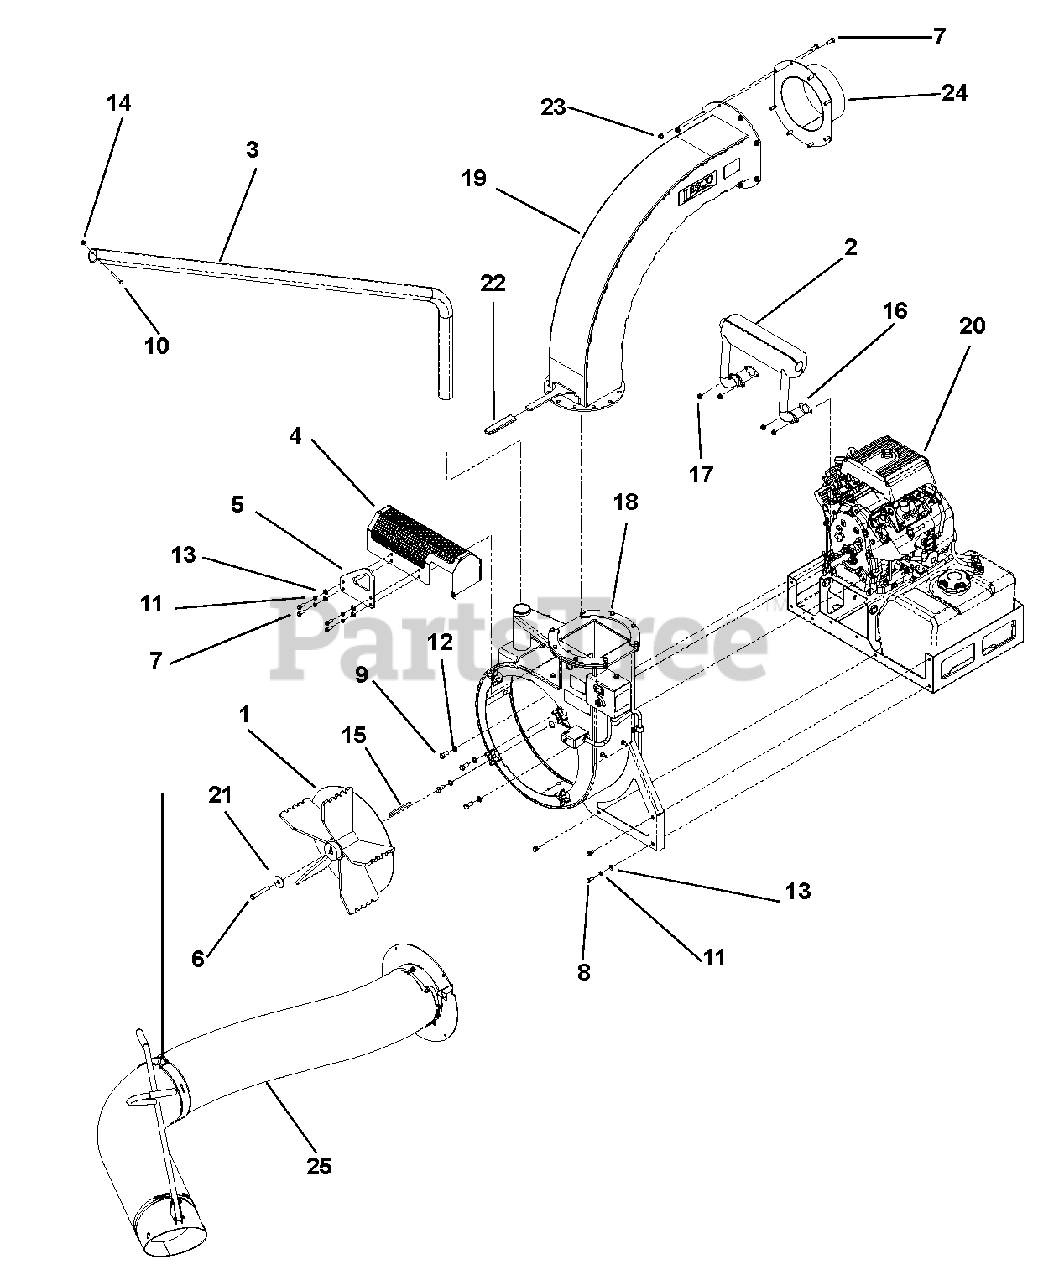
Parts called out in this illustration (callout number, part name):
1	Weldment, Impeller 5 Blade Balanced
1	Weldment, Impeller 4 Blade Balanced
2	Muffler, Subaru 20 HP & 22 HP
2	MUFFLER, SUBARU
3	Support Arm
4	Weldment, Muffler Shield
5	Blower Lift Plate
6	Bolt, Hex .44-20 x 3.00 Grade YZ EP80
6	Bolt, Hex .38-24 x 3.00 Grade YZ EP80
7	Bolt, Hex .31-18 x 1.00 Grade 5 YWZC
8	Bolt, Hex .31-18 x .75 Grade 5 YWZC
9	Bolt, Hex .44-14 x .88 Grade 5 EP30
10	Bolt, Hex .25-20 x 2.50 Grade 5 YWZC
11	Washer, Lock .31 x .078 Reg YWZC
12	Washer, Lock .44 x .109 Reg YWZC
13	Washer, Flat .344 x .688 x .065 Stl, YWZC
14	Nut, .25-20 Nyloc Flange
15	Key, Square .250 x 4.00
16	Gasket, Exhaust Manifold EH65
17	Nut, Exhaust Manifold EH65
18	Fan Housing Assembly, 22 HP
18	Fan Housing Assembly, 20 HP
19	Assy, Exhaust Tall W/Decals
20	Engine and Base Assembly, 22 HP
20	Engine and Base Assembly, 20 HP
21	Washer, Area Vac 35, 29/64 x 13/4X
22	Grip, Rubber Lever
23	Nut, .31-18 Nyloc Flange YXZC
24	Weldment, Discharge 8"
25	Vacuum Hose Assembly, 12"
25	Vacuum Hose Assembly, 10"
